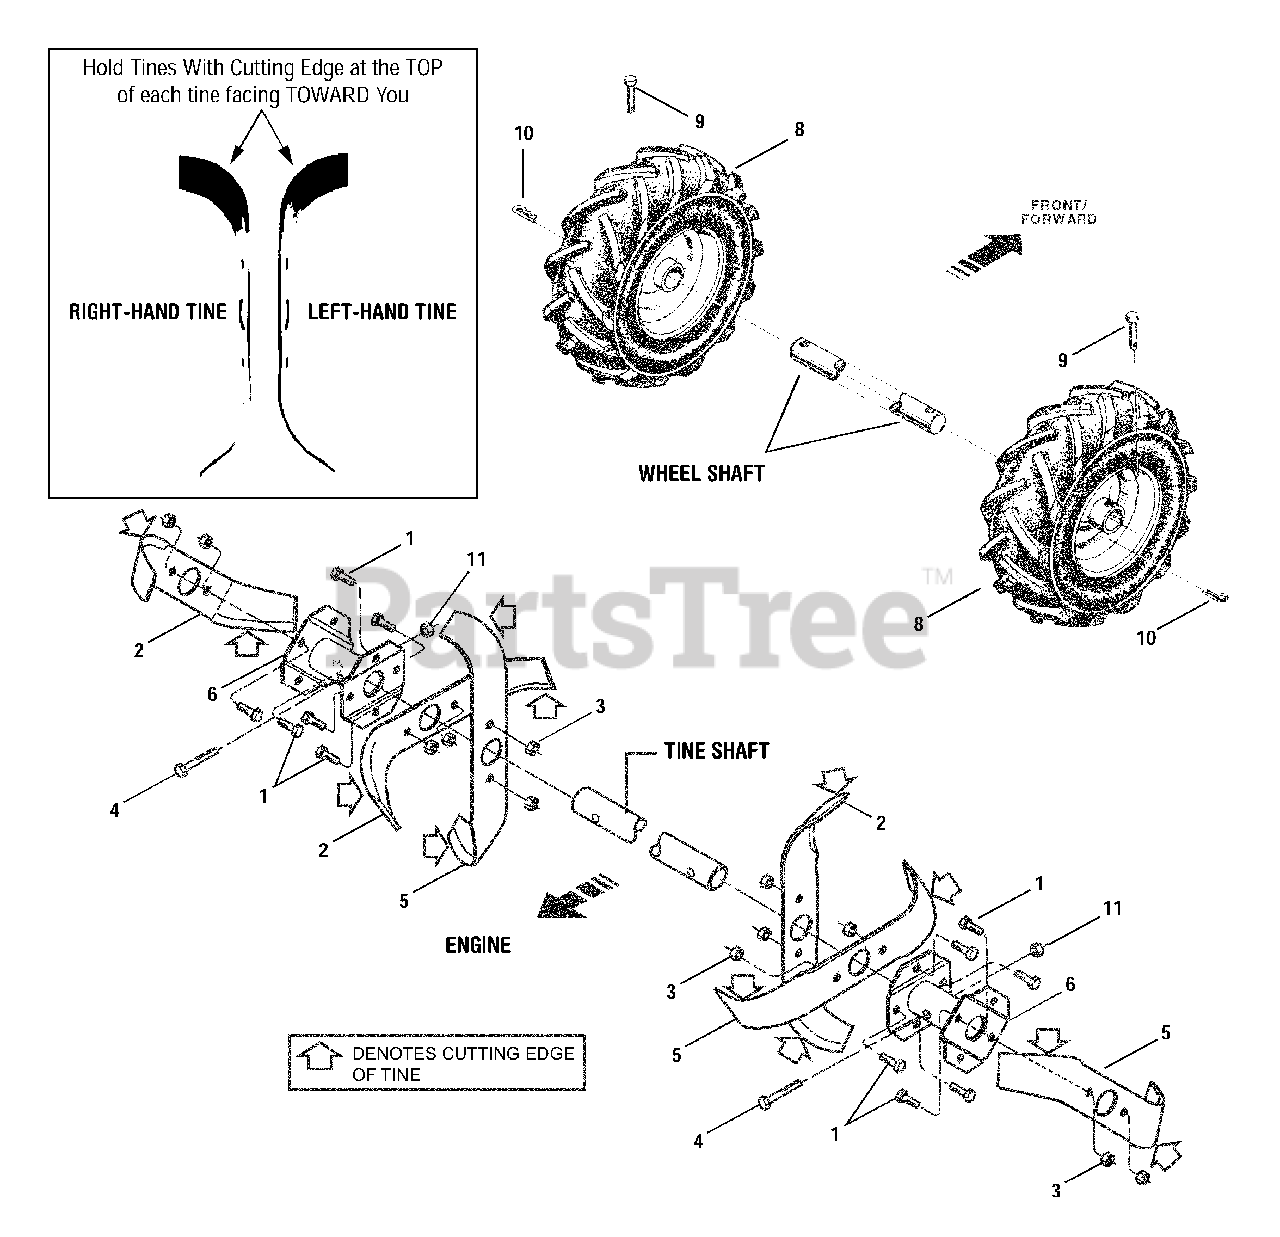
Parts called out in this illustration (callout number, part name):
1	Hex Hd. Screw, 5/16-18 x 3/4, Grade 5
2	Single Tine - Right Hand
3	Hex Lock Nut, 5/16-18
4	Hex Hd. Screw, 3/8-16 x 2
5	Single Tine - Left Hand
6	LH Tine Holder
7	RH Tine Holder
8	Wheel & Tire Ass'y - Left/Right Side
9	Clevis Pin,.312" x 1-3/4"
10	Hair Pin Cotter
11	Hex Lock Nut, 3/8-16
